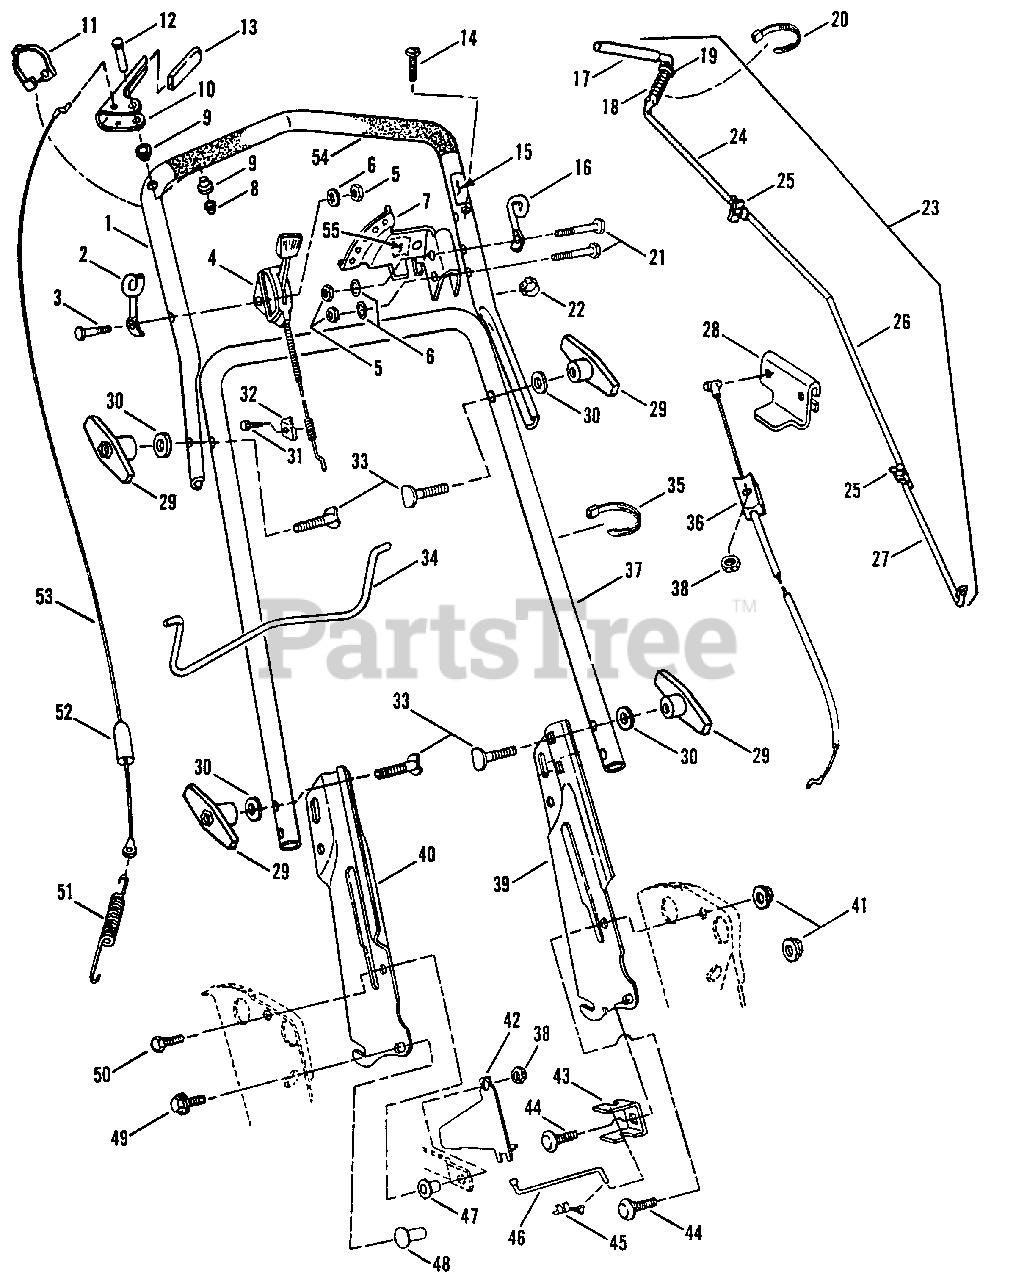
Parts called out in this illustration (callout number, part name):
1	HANDLE, Upper
2	GUIDE, Pull Rope (Right Side)
3	SCREW, 1/4-20 x 2 Hex Head Cap, Grade 5
4	CONTROL, Throttle 48.0" (Briggs 6 HP California Model)
4	CONTROL, Throttle 49.75" (Briggs 6 HP OHV (Over Head Valve) Model)
5	NUT, 1/4-20 Hex
6	WASHER, 1/4 Internal Tooth Lock
7	SECTOR, Speed
8	PUSH-NUT
9	BUSHING
10	HANDLE, Wheel Drive
11	CLAMP, 7/8 Double Cable
12	PIN, Clutch Cable
13	GRIP, Wheel Drive Handle
14	SCREW, 5/16-24 x 1-1/2 Machine, Grade 5
15	DECAL, Blade Control (Left Side)
16	GUIDE, Pull Rope (Left Side)
17	GRIP, Speed Control Handle
18	SPRING, Speed Control
19	WASHER, 3/8" Flat
20	TIE, Wire
21	SCREW, 1/4-20 x 1-1/2 Hex Head Cap, Grade 5
22	CLIP, Cable Wiring
23	ASSEMBLY, Speed Control Lever
24	ROD, Upper
25	WING-NUT, 1/4-20
26	ROD, Intermediate
27	ROD, Lower
28	CLIP, Blade Control
29	T-KNOB, 5/16-18 Thread
30	WASHER, 5/16 Internal Tooth Lock
31	SCREW, #10-32 x 5/8" Hex Head Cap
32	CLAMP, Casing
33	SCREW, 5/16-18 x 1-7/8 Curved Head, Grade 2
34	CONTROL, Blade
35	TIE, Wire
36	CABLE, Blade Control
37	HANDLE, Middle
38	NUT, 5/16-24 Hex Center Lock, Grade 5
39	BRACKET, Middle Handle (Left Side)
40	BRACKET, Middle Handle (Right Side)
41	NUT, 5/16-18 Hex Flange Lock, Grade 5
42	GUIDE, Lower V-Belt
43	ANCHOR, Speed Control
44	BOLT, 5/16-18 x 5/8 Carriage, Grade 5
45	CLIP, Transfer Rod
46	ROD, Transfer
47	BUSHING, Differential
48	TEE-NUT, 5/16-18 Thread
49	BOLT, 5/16-18 x 3/4 Hex Flange Lock, Grade 5
50	SCREW, 5/16-24 x 1" Hex Head Cap, Grade 5
51	SPRING, Clutch
52	COVER, Vinyl
53	CABLE, Clutch Pull (Z-Bend)
54	GRIP, Foam
55	DECAL, Speed Select
